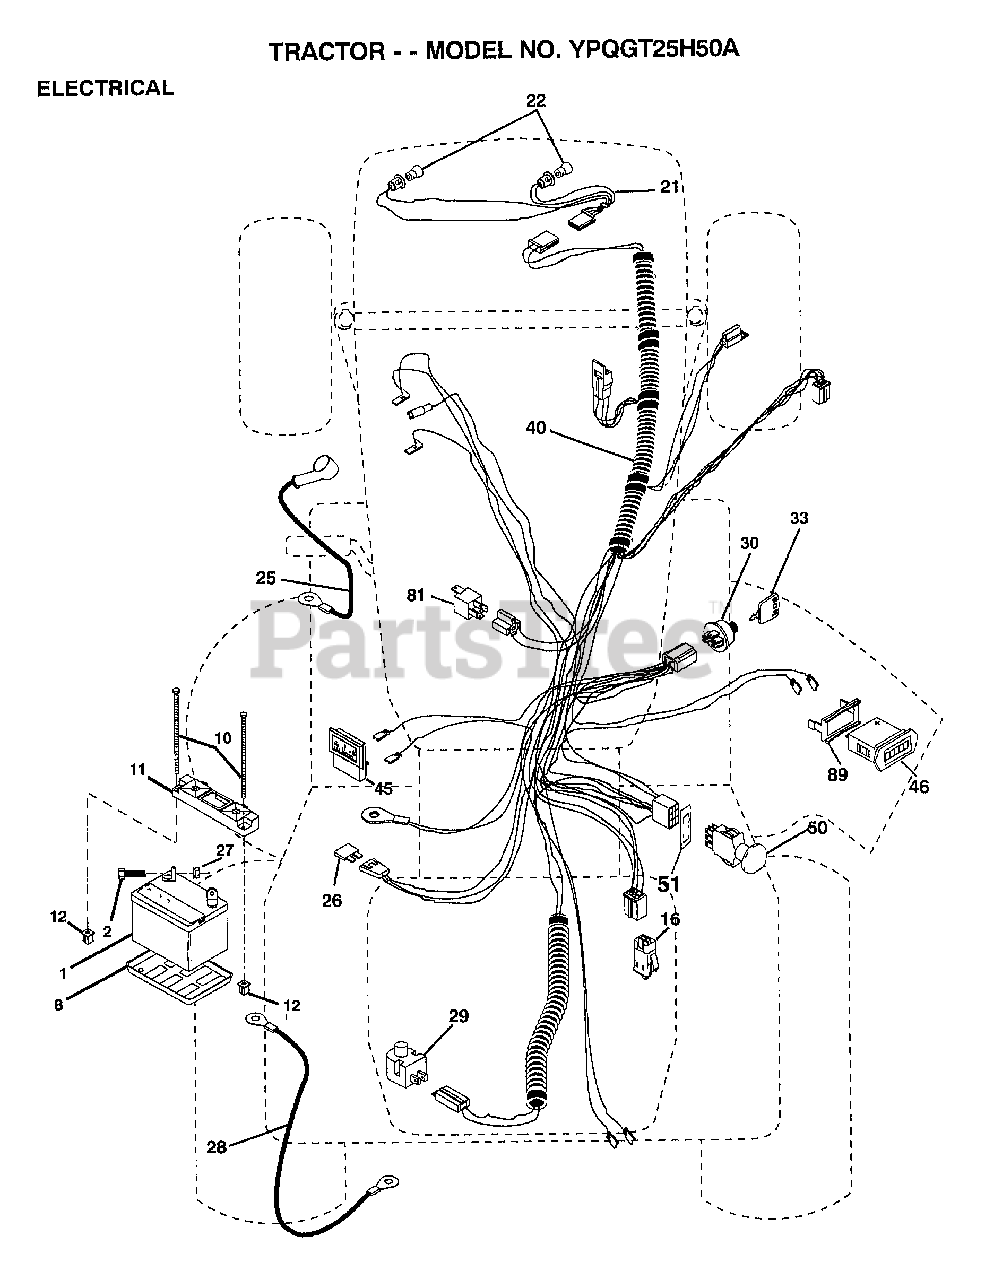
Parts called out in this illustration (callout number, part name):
2	BOLT LT
8	"TRAY T, BATTERY"
11	HOLDDOWN BATTERY
16	SWITCH INTERLOCK
21	HARNESS.ASM.LIGHT.W/4152J
22	HEADLAMP BULB
25	CABLE.BOOT.ASM.
26	FUSE HYT
27	NUT
28	"CABLE BATTERY,GRD"
29	SWITCH.PLUNGER
30	SWITCH.IGN.
33	KEY MLD GEN DELTA
40	HARNESS.ING.VGT.
45	AMMETER
46	METER HOUR
50	PTO SWITCH.BLK
51	RING RETAIN PTO
81	RELAY ASSY T
89	BRACKET SNAP
